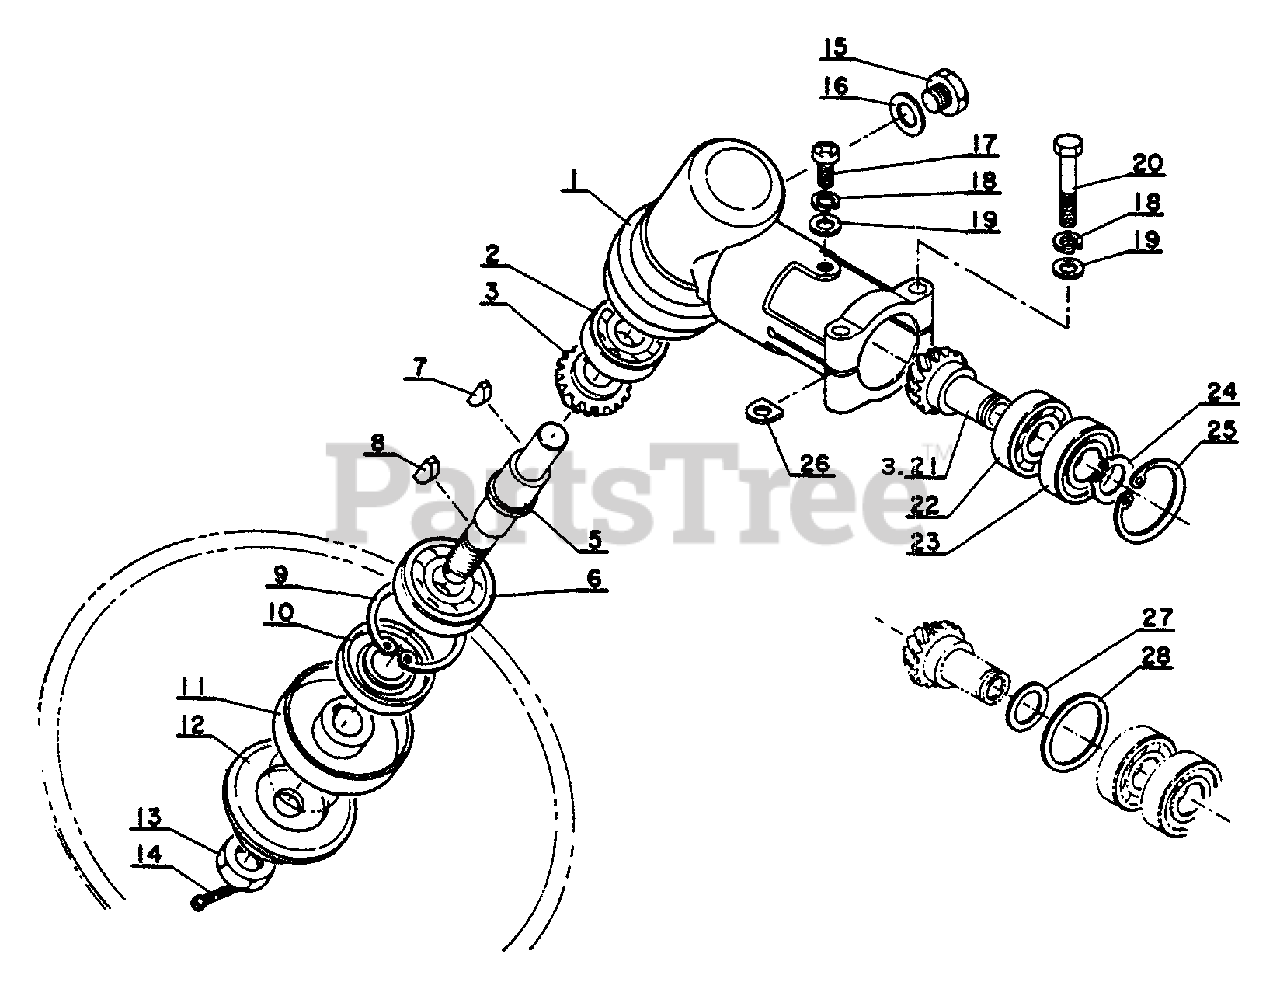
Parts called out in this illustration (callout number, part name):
1	CASE, GEAR
2	BEARING, BALL - 6000
3	GEAR SET
4	WASHER
5	DRIVESHAFT
6	BEARING, BALL - 6201
9	RING, RETAINING - 32
10	SEAL, OIL
11	ADAPTOR, BLADE - UPPER
12	ADAPTOR, BLADE - LOWER
13	NUT - 10 -- LEFT HAND
14	PIN, SPLIT - 2X22
15	BOLT - 8X6
16	GASKET
17	SCREW - 5X10
18	LOCKWASHER - 5
19	WASHER - 5
20	BOLT - 5X30
21	GEAR SET
22	BEARING, BALL - 6001
23	BEARING, BALL - 6001
24	RING, RETAINING - 12
25	RING, RETAINING - 28
